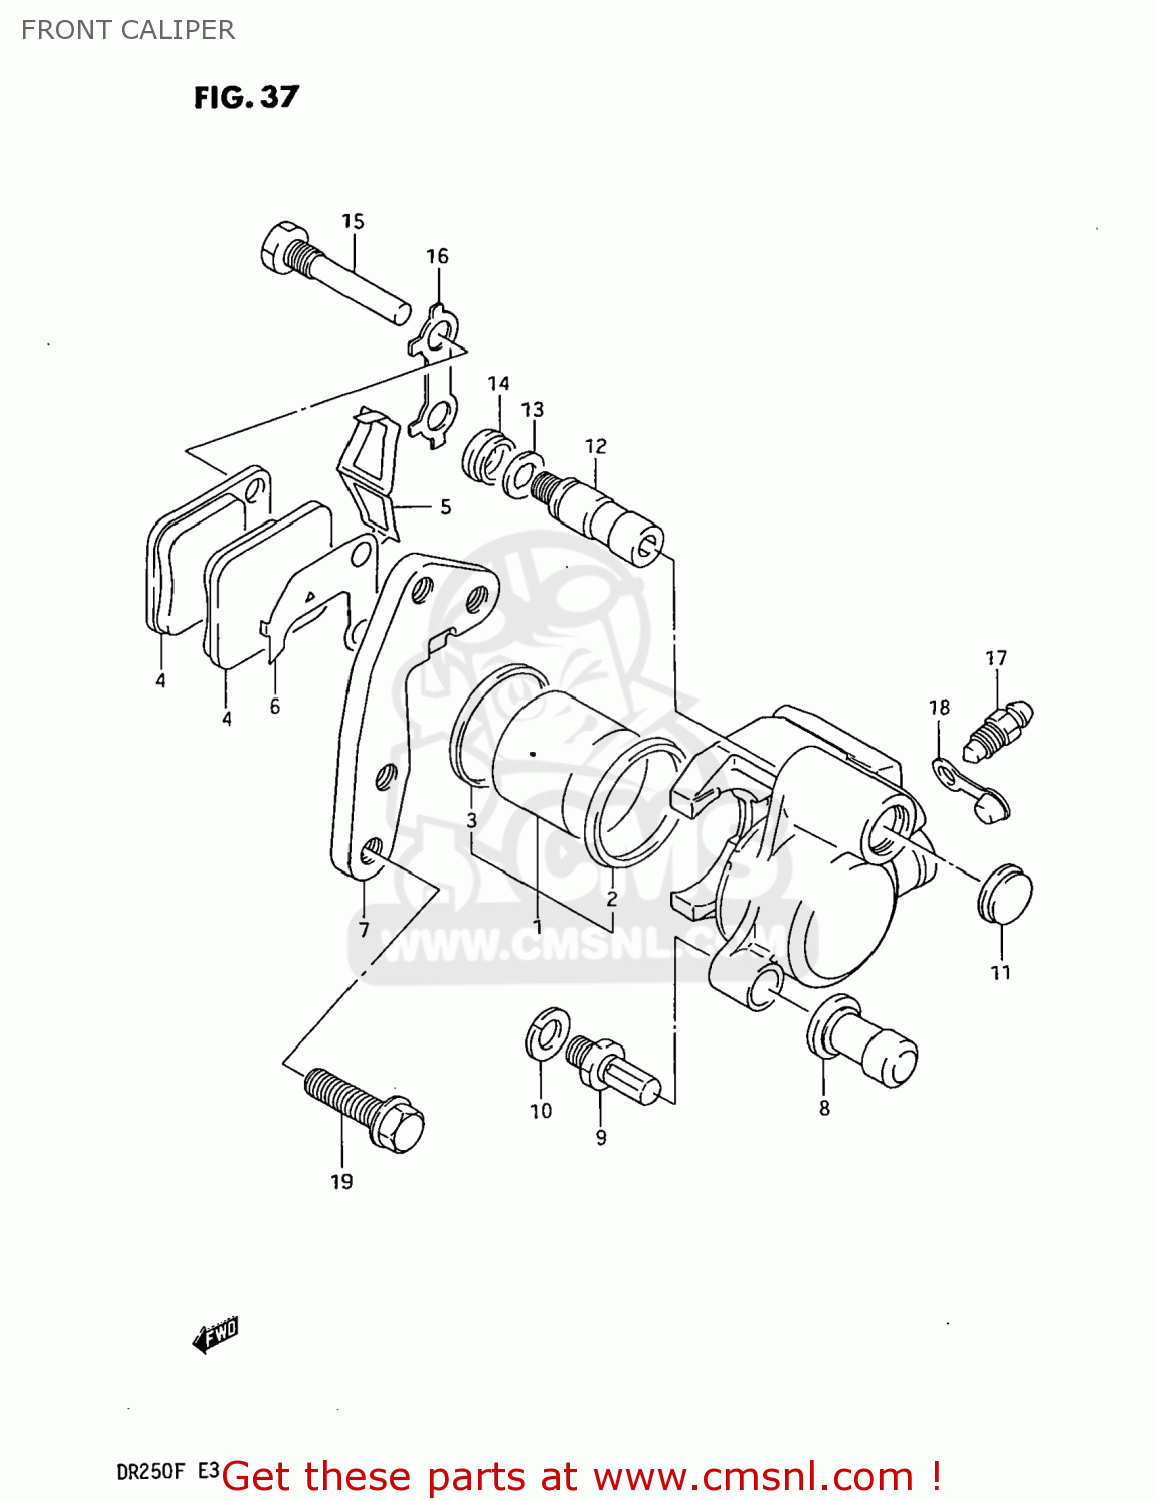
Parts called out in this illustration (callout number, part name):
1	PISTON SET,CALIPERS
2	SEAL,PISTON
3	BOOT,PISTON
4	PAD
5	SPRING,PAD
6	SHIM
7	BRACKET
8	BOOT
9	BOLT,PIN
10	WASHER,WAVE
11	DUST SEAL
12	PIN
13	SPRING,FRICTION
14	BOOT,PIN
15	PIN,HANGER
16	WASHER
17	BLEEDER
18	CAP,BLEEDER
19	BOLT
